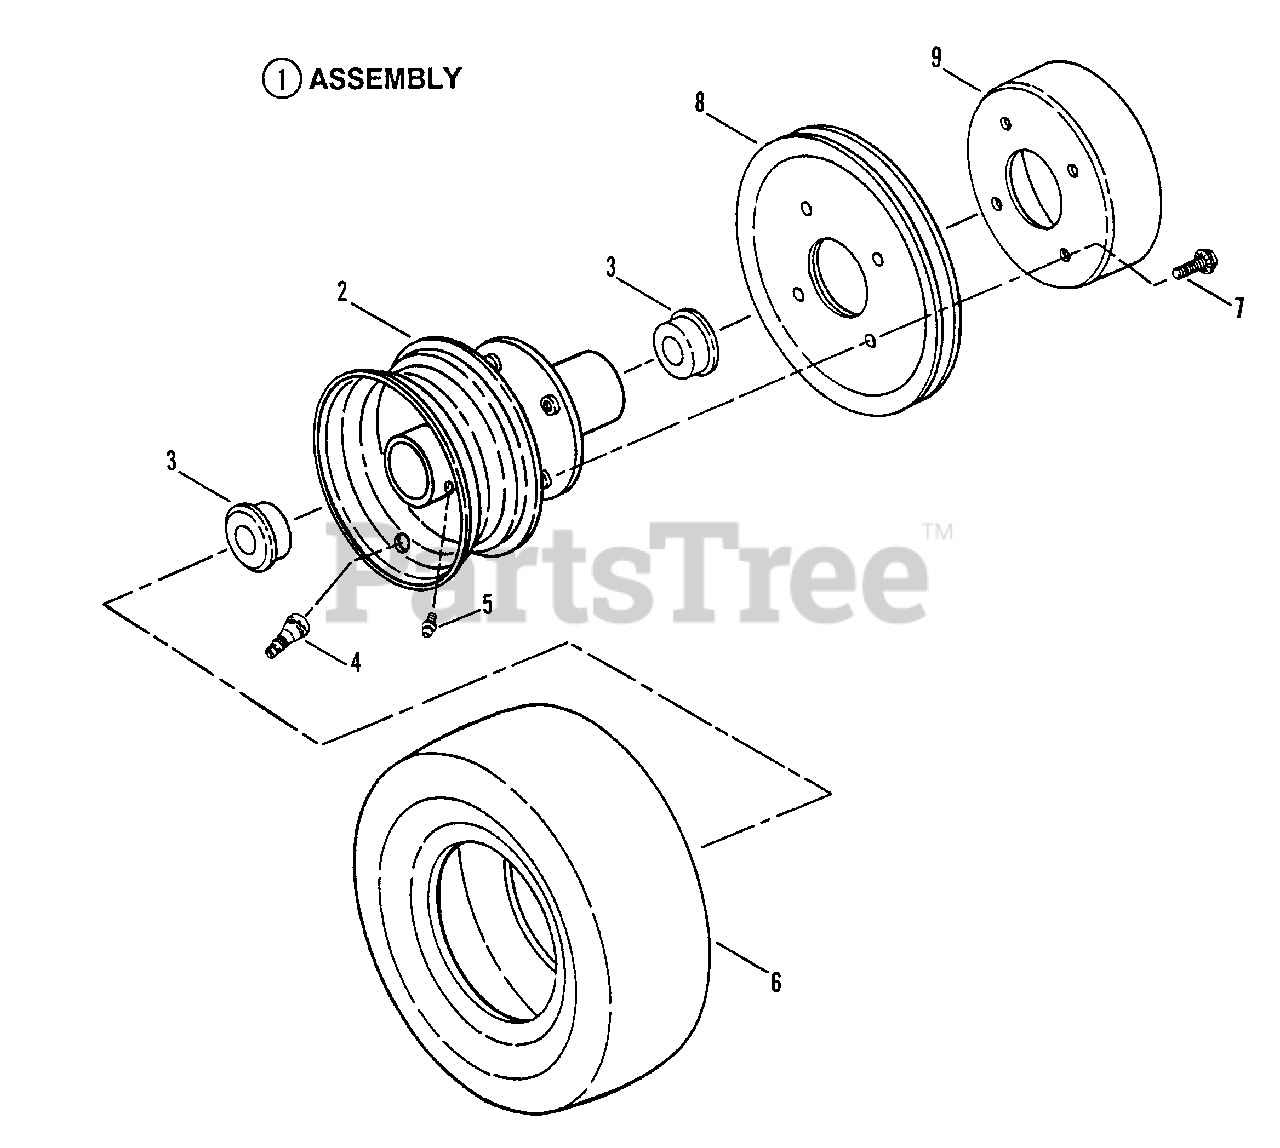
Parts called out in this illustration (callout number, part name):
1	ASSEMBLY, Tire & Hub
2	HUB, Weldment
3	BEARING, Wheel
4	VALVE, Air (Snap-In)
5	FITTING, Lube
6	TIRE, 4.10/3.50 x 6" Tubeless
7	BOLT, 5/16-18 x 1" Hex Flange Lock, Grade 5
8	PULLEY, 8"
9	DRUM, Brake, 6"
